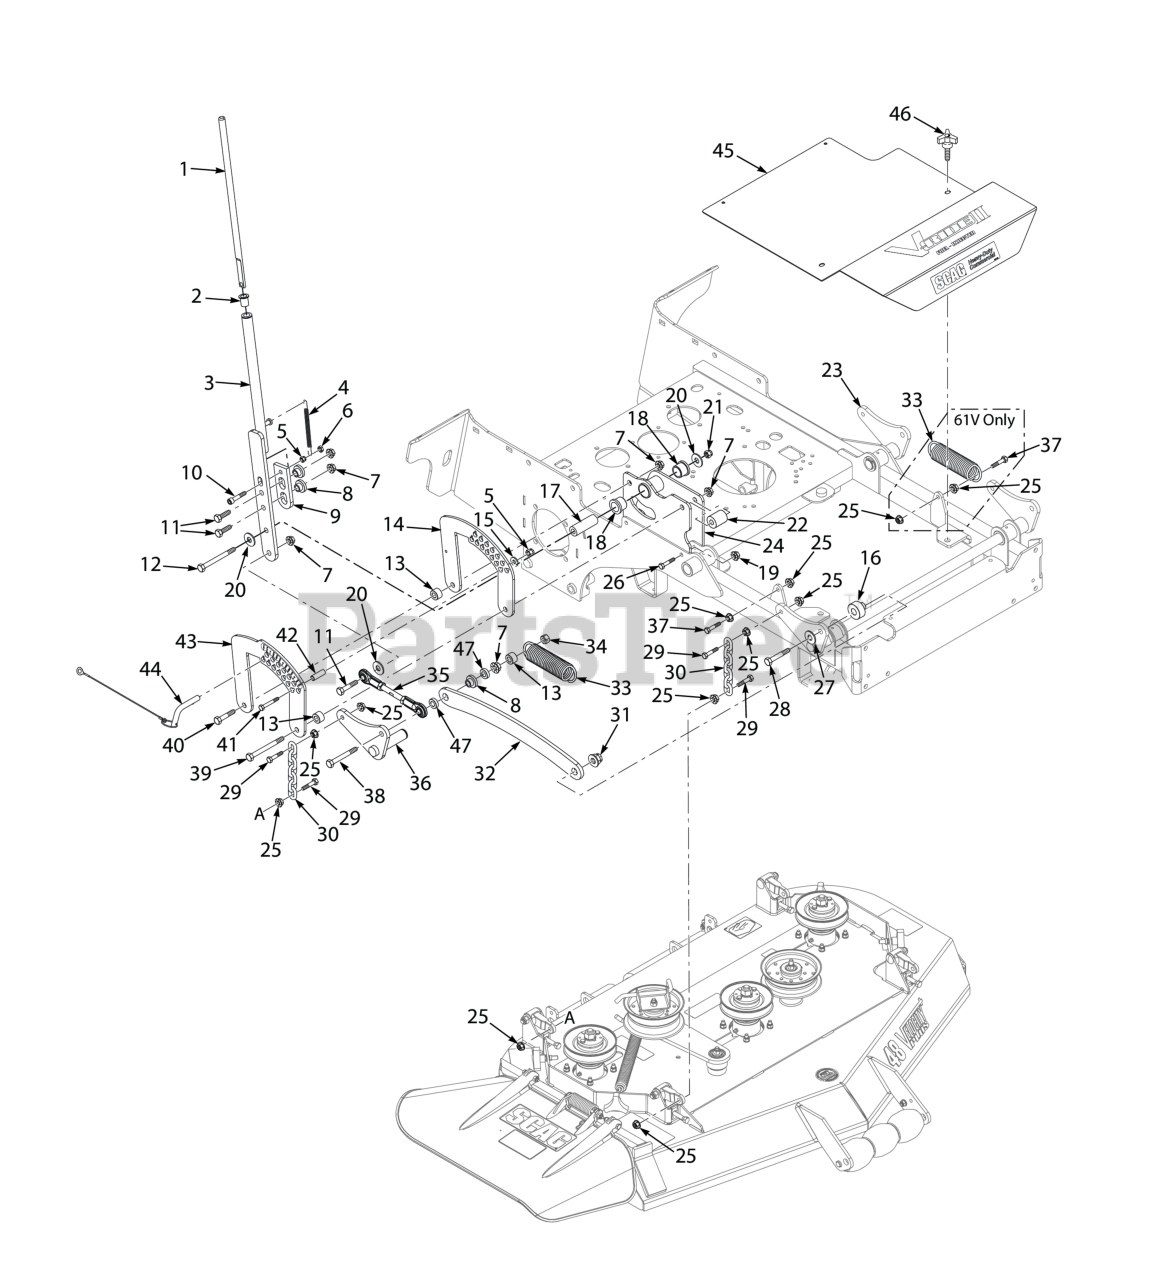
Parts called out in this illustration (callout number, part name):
1	Actuator Rod, Deck Latch
2	Bearing, .625 ID Plastic
3	Handle Weldment, Deck Latch
4	Spring, Deck Latch
5	HEX NUT, ELASTIC STOP LOCK, 3/8-16
6	Bolt, Hex Head 3/8-16 x 1" Ser. Flg.
7	Nut, Hex Serrated Flange 1/2-13
8	Bushing, Deck Lift
9	Deck Latch, Outer
10	Capscrew, Socket Head 3/8-16 x 1-3/4"
11	Bolt, Hex Head 1/2-13 x 1-3/4"
12	Bolt, Hex Head 1/2-13 x 4-1/4"
13	Spacer
14	Bracket, Deck Height
15	Flatwasher, 3/8" Special (.391 x .938 x .105)
16	Bushing, Deck Lift
17	Sleeve, Brake Pivot
18	Bearing, Plastic
19	Nut, Flange Elastic Stop Nut, 3/8-16
20	Flat Washer, 1/2 (.562 x 1.375 x .109)
21	HEX LOCKNUT, ELASTIC STOP, 1/2-13
22	Spacer, Decklift Pivot
23	Arm Weldment, LH
24	Deck Lift Pivot Assy.
25	NUT, 3/8-16 SERRATED FLANGE HEX HEAD
26	Bolt, Hex Head, 3/8-16 x 1 Gr. 5
27	Washer, Flat, 1/2-.562 x 1.375 x .109 HD
28	Bolt, Hex Hd. 1/2-13 x 2-1/2" (lower)
29	Bolt, Hex Head 3/8-16 x 1-1/2" B&S 32BV
30	CHAIN ASSY
31	Nut, Elastic Stop 1/2-13, (STT-52 & STTII-52)
32	Link, Deck Lift
33	Spring, Deck Lift
34	Locknut, Hex 1/2-13 Center Lock
35	Link, Deck Lift
36	Arm Weldment, RH
37	Bolt, Hex Head 3/8-16 x 1-1/2" Grade 8 Black
38	Bolt, Hex Head 1/2-13 x 3-1/2"
39	Bolt, Hex Head 1/2-13 x 4" (lower)
40	Hex Head Bolt, 1/2-13 x 2"
41	Bolt, Hex Head 3/8-16 x 2-1/4" - 61"
42	Bushing, .502 O.D.
43	Bracket, Deck Height - Outer
44	Pin Assy. w/Lanyard
45	Belt Cover w/Decals
46	Knob, w/stud 3/8-16 x 1-1/4"
47	Spacer, Radiator
